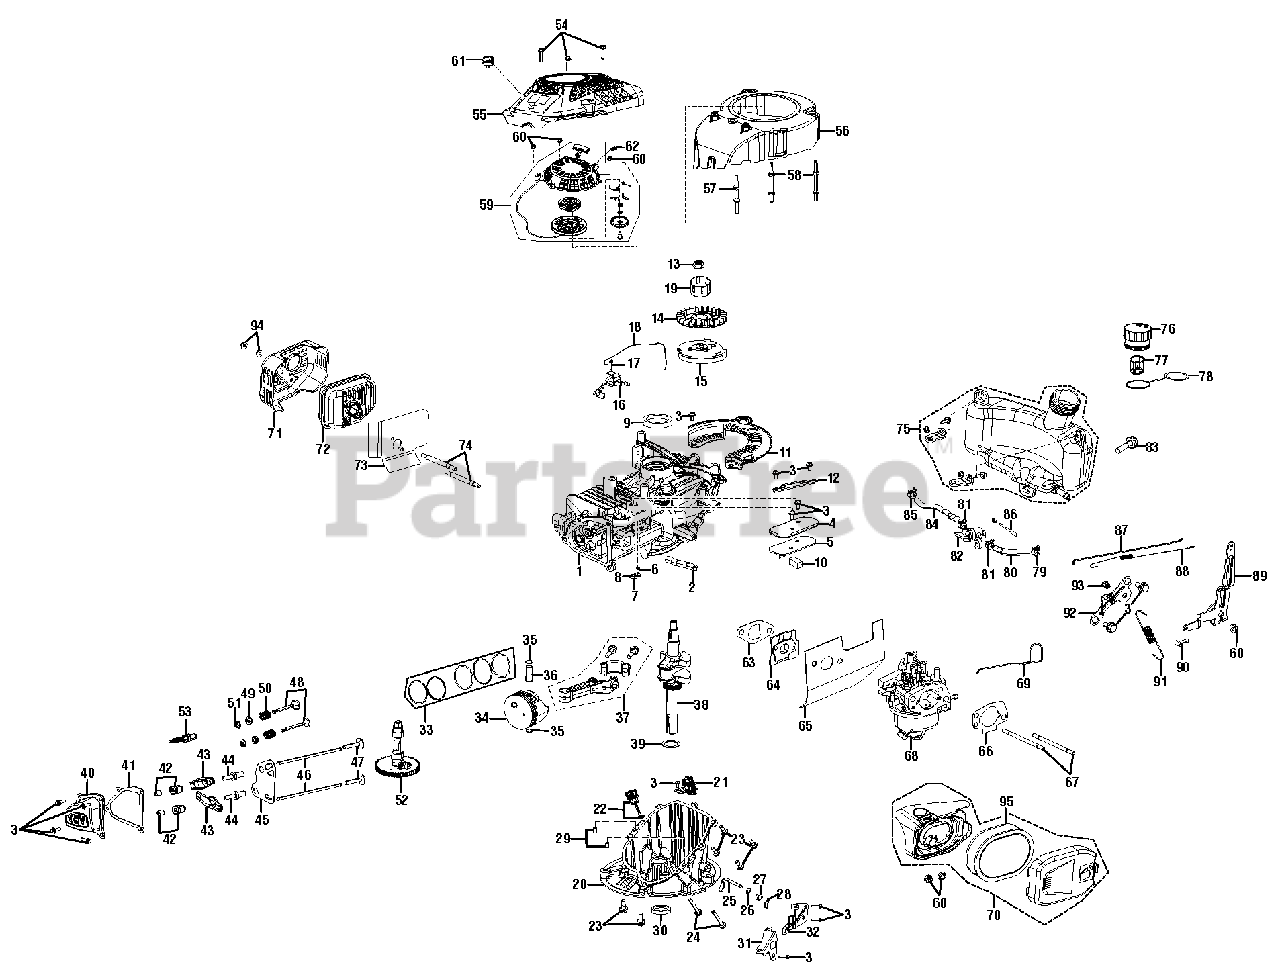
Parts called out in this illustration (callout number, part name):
1	Crankcase Assembly
4	Breathe Groove Cover Plate
5	Breathe Groove Gasket
6	Bolt (Cross-Stitch)
8	Valve Reed Stopping Plate
10	Breathe Groove Strainer
15	Flywheel Subassembly
18	Ignition Coil Wire
20	Crankcase Cover
21	Governor Gear Assembly
22	Dipstick Assembly
31	Fuel Valve Holder
35	Piston Pin Clip
38	Crankshaft Assembly
40	Cylinder Head Cover
41	Cylinder Head Cover Gasket
42	Valve Adjusting Nut
44	Valve Adjusting Bolt
49	Valve Spring Seat
52	Camshaft Assembly
59	Recoil Starter Assembly
61	Stop Engine Switch
63	Insulator Plate Gasket
64	Carburetor Insulator Plate
65	Insulator Plate Gasket
66	Carburetor Gasket
68	Carburetor Assembly
71	Muffler Outer Cover
72	Muffler Assembly
73	Exhaust Outlet Gasket
76	Fuel Tank Cover
77	Fuel Tank Strainer
78	Fuel Tank Lock Ring
86	Stop Engine Switch Grounding Wire
88	Throttle Valve Returning Spring
89	Governer Support Subassembly
90	Governer Support Bolt
91	Governer Spring
92	Throttle Control Bottom Plate Subassembly
